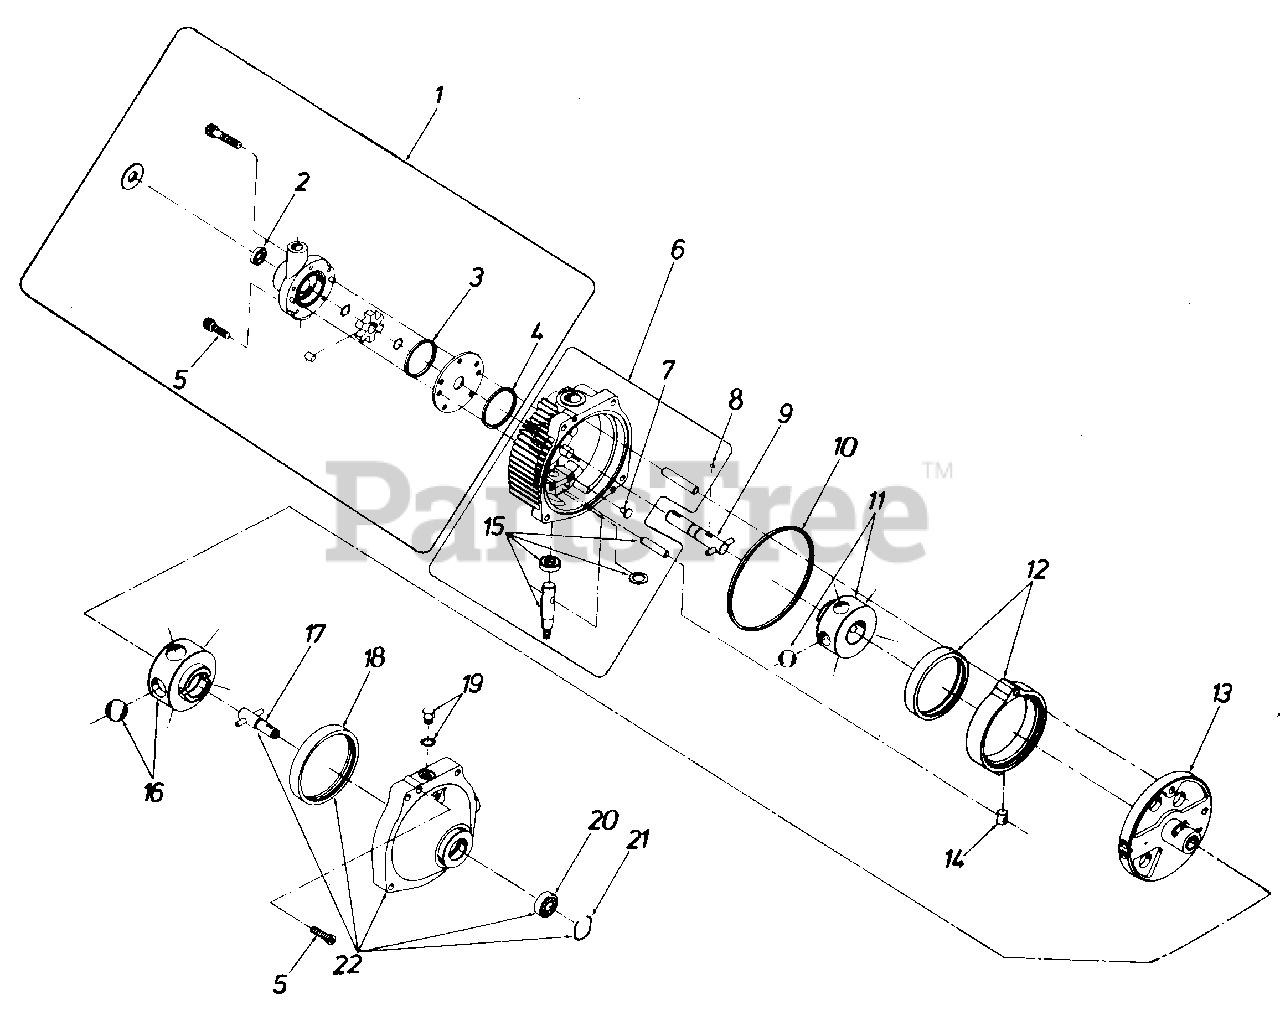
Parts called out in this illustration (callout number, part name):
1	Charge Pump Kit
2	Oil Seal
3	Square Cut Seal Ring .036
4	Square Cut Seal Ring .038
5	Socket Head Cap Screw 5/16-18 x 1.25" Long
6	Cover Subassembly
7	Button
8	Drive Pin
9	Input Shaft Subassembly
10	Square Cut Seal Ring .166
11	Pump Rotor Ball Sub-assembly
12	Cam Ring Subassembly
13	Pintle Subassembly
14	Cam Ring Insert
15	Control Shaft Kit
16	Motor Rotor Ball Sub-assembly
17	Output Shaft Sub-assembly
18	Motor Race
19	O-Ring Plug Subassembly
20	Ball Bearing (Output)
21	Retaining Ring
22	Body Subassembly
